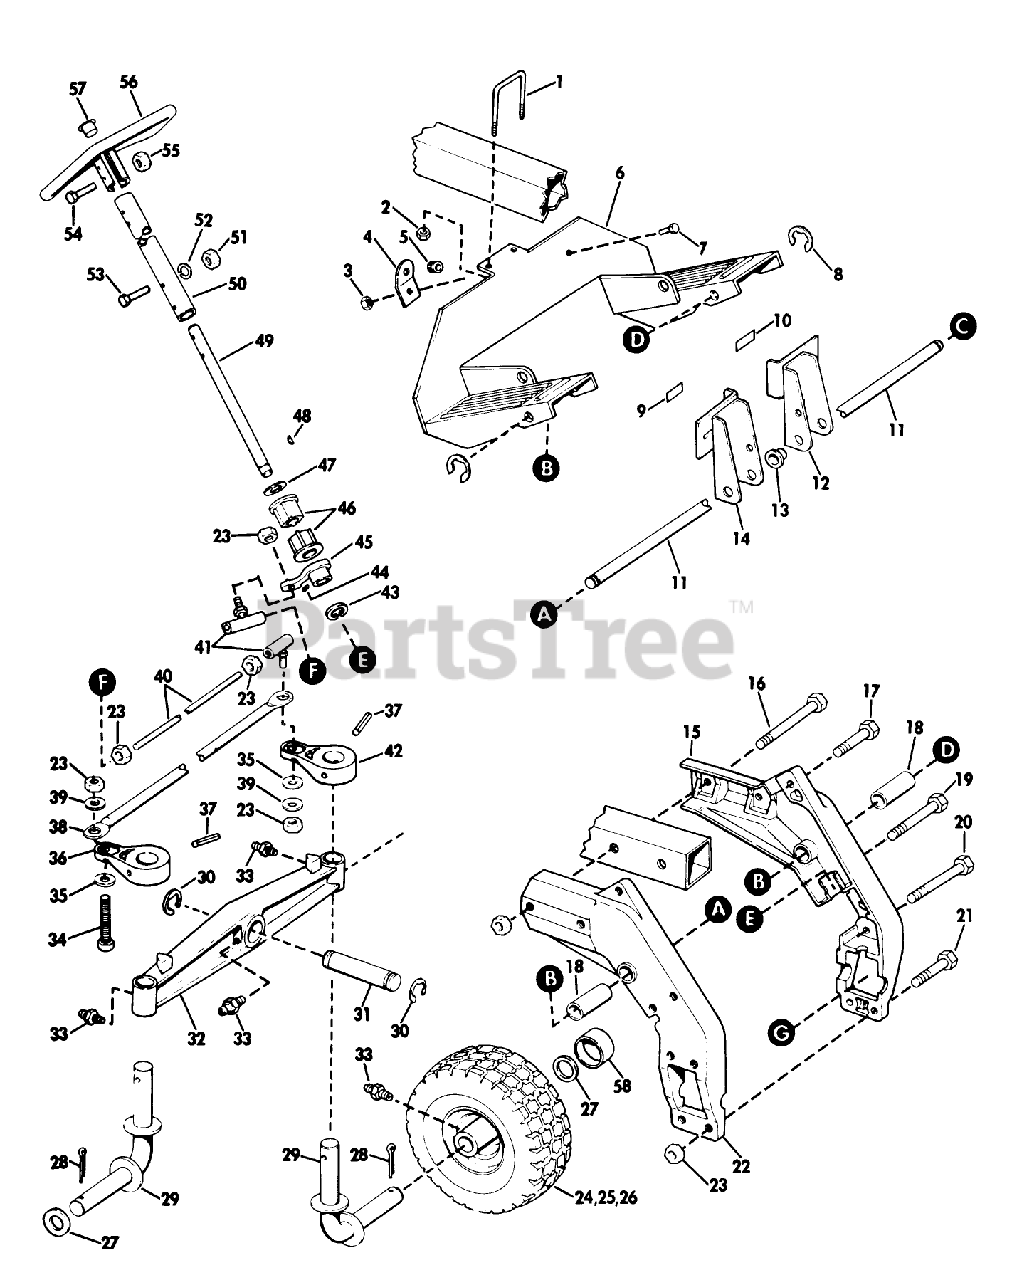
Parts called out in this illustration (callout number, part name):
5	Bushing
33	Grease Fitting
34	Screw-King Pin
55	Nut-Steering Shaft
